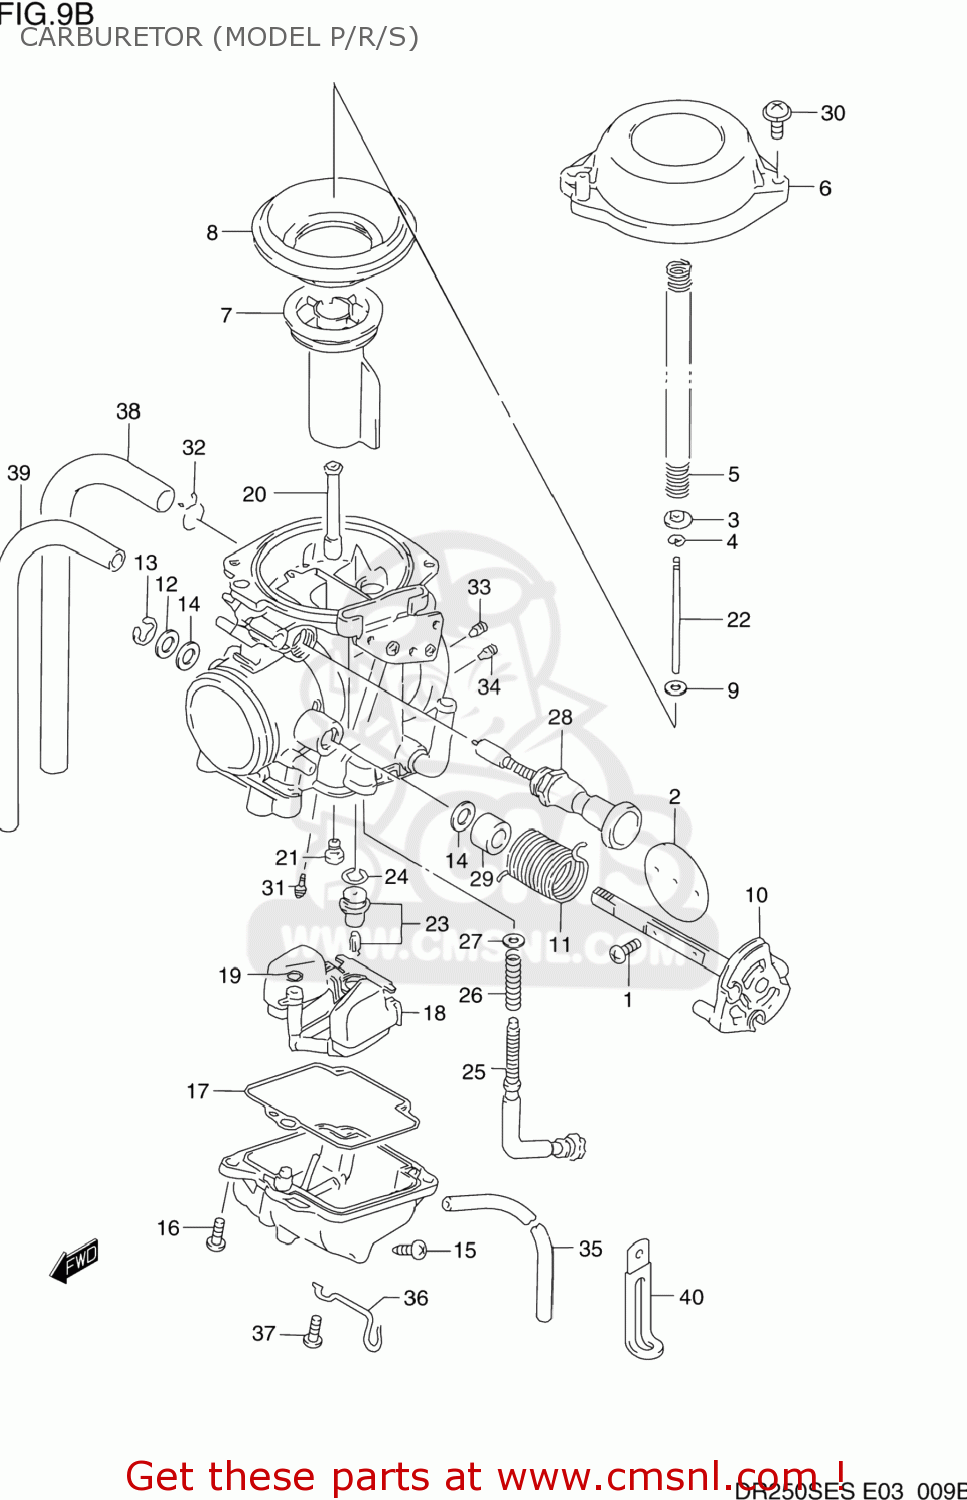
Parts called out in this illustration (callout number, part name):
1	SCREW
2	VALVE,THROTTLE (115)
3	RING
4	E RING
5	SPRING
6	COVER,DIAPHRAGM
7	VALVE PISTON
8	DIAPHRAGM
9	RING
10	SHAFT ASSEMBLY
11	SPRING
12	GASKET,THROTTLE SHAFT (NAS)
13	E RING
14	SEAL
15	SCREW,DRAIN
16	SCREW
17	GASKET,FLOAT CHAMBER (NAS)
18	FLOAT ASSY
19	O RING
20	JET,NEEDLE (O-8)
21	JET,MAIN(130)
22	NEEDLE JET (5CD22)
23	VALVE ASSEMBLY,NEEDLE
24	O-RING,NEEDLE VALVE
25	ADJUSTER
26	SPRING,THROTTLE SCREW
27	WASHER,STARTER SHAFT
28	PLUNGER ASSEMBLY
29	RING
30	SCREW
31	JET,PILOT(37.5)
32	CLIP
33	JET,AIR(1.25)
34	JET,AIR(0.6)
35	HOSE
36	CLIP
37	SCREW
38	HOSE
39	HOSE
40	CLAMP
